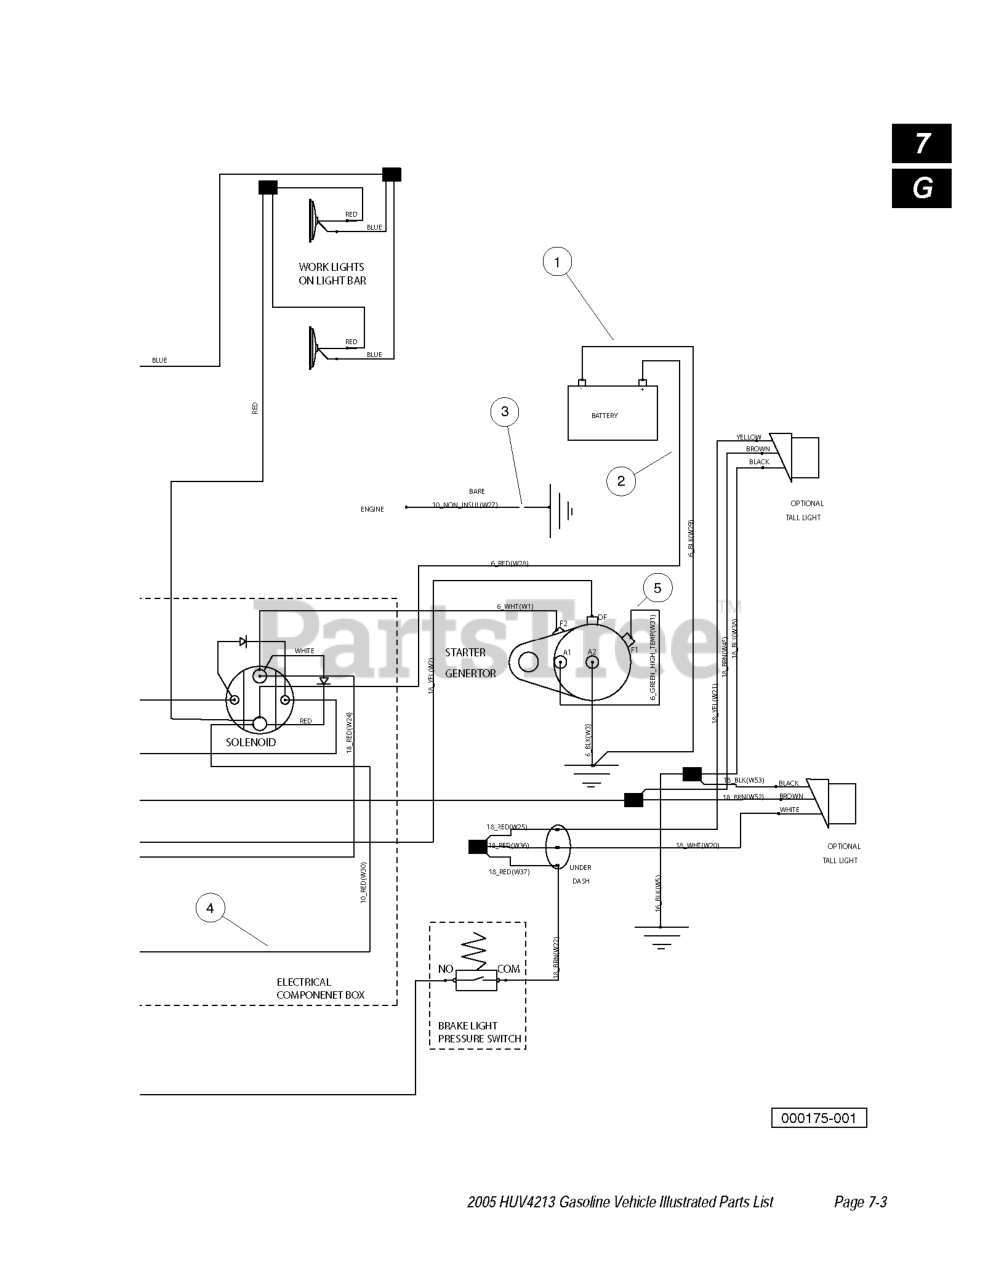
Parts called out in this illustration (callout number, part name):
1	WIRE ASSY, #6 BLACK
2	WIRE ASSY #6 RED
3	WIRE ASM
4	WIRE ASSY, #10 RED
5	WIRE ASSY, #6 GREEN
6	ASM, WIRE HARNESS
